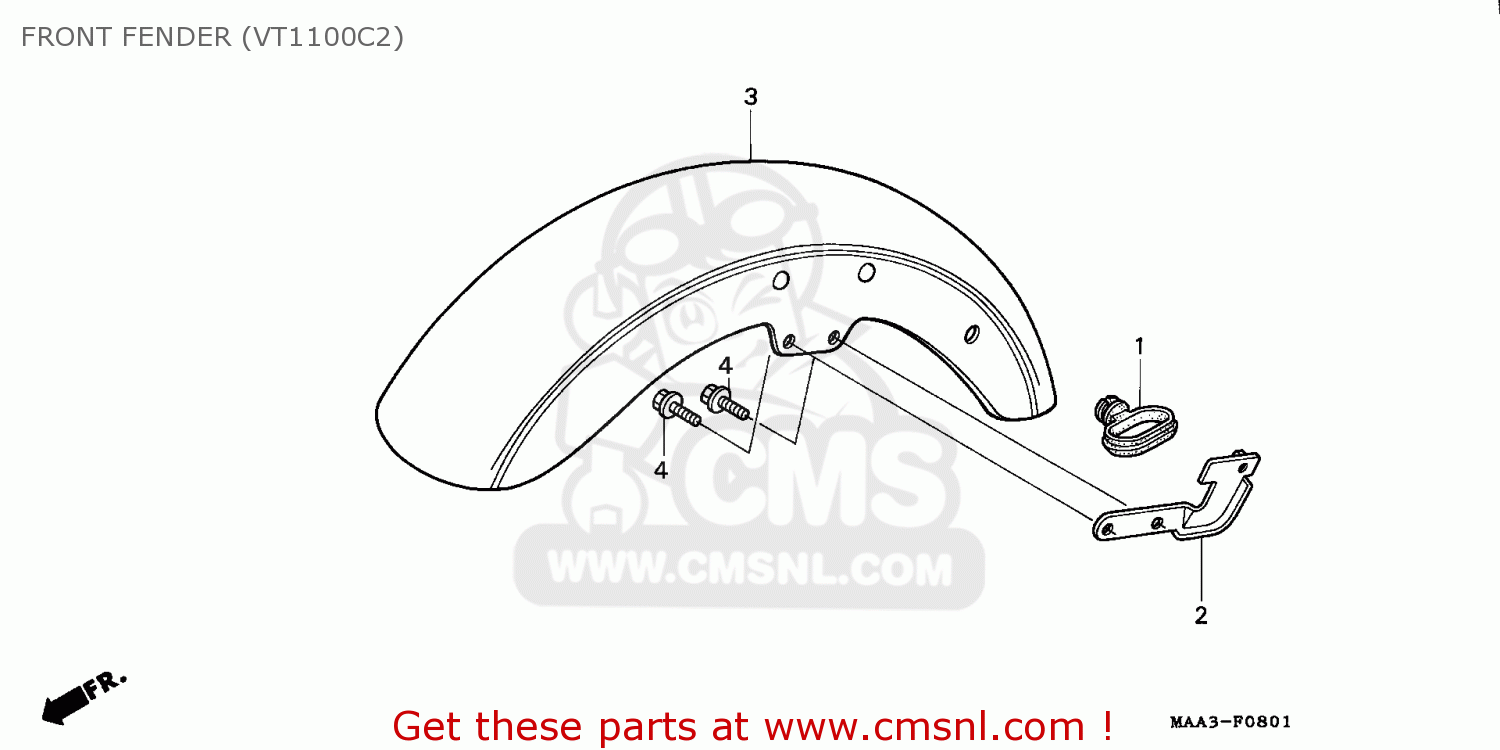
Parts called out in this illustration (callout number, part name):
1	GUIDE,FEND.CABLE
2	CRIP,L.FR.BRKT.HO
3	SET ILLUST*TYPE5*
4	BOLT,FLANGE,6X16
